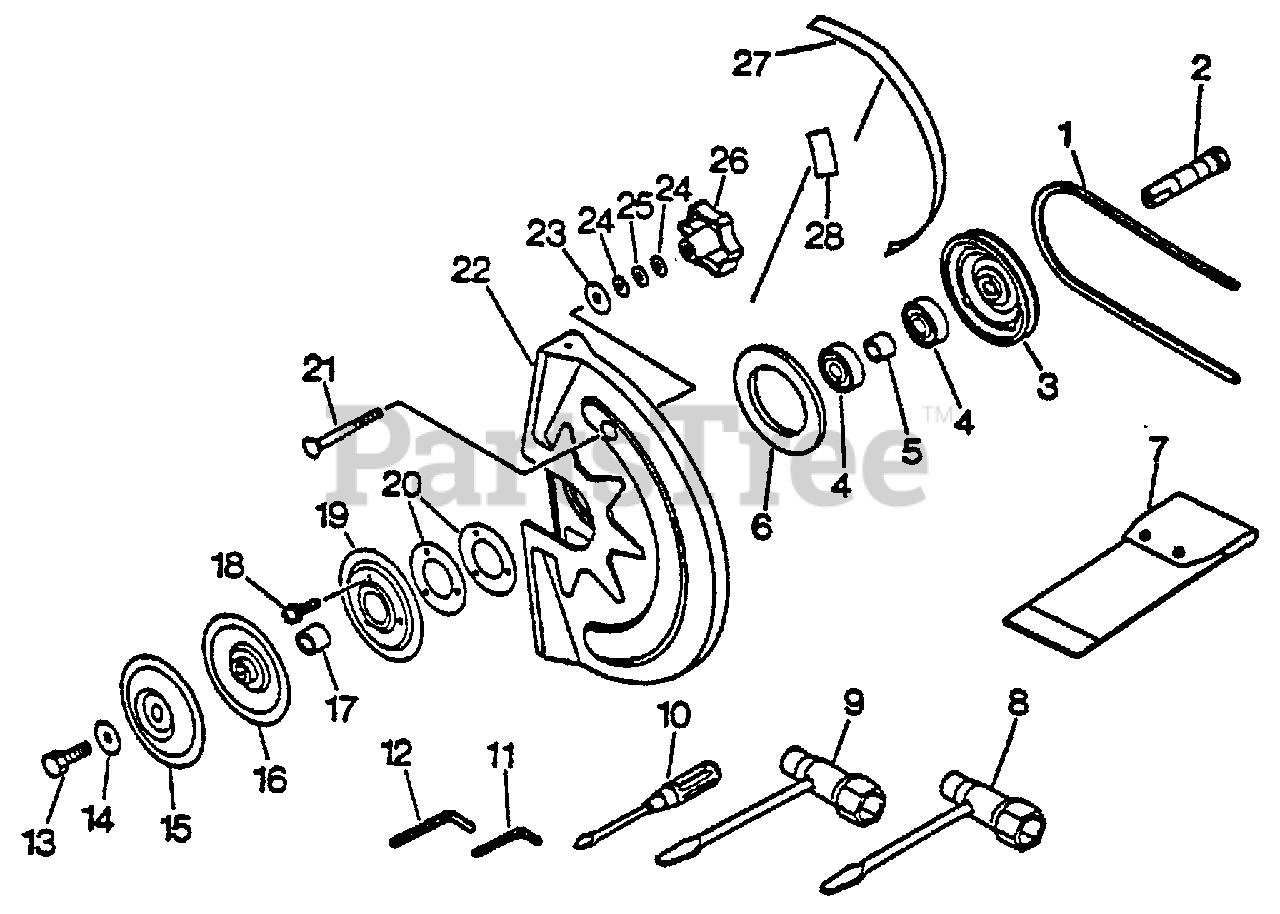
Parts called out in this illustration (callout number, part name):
4	BEARING, BALL 6203
5	SPACER
7	BAG, TOOL
8	T-WRENCH 13×19×180
9	WRENCH, T 17×19 MM
10	SCREWDRIVER, SLOTTED
11	WRENCH, ALLEN 4 MM
12	WRENCH, ALLEN 5 MM
15	FLANGE, CUTTER
16	FLANGE, CUTTER
18	SCREW 4×14
19	PLATE
22	COVER, BLADE
24	WASHER 10.5×18×1.6
25	WASHER, SPRING 10
27	LABEL
28	LABEL - ECHO
